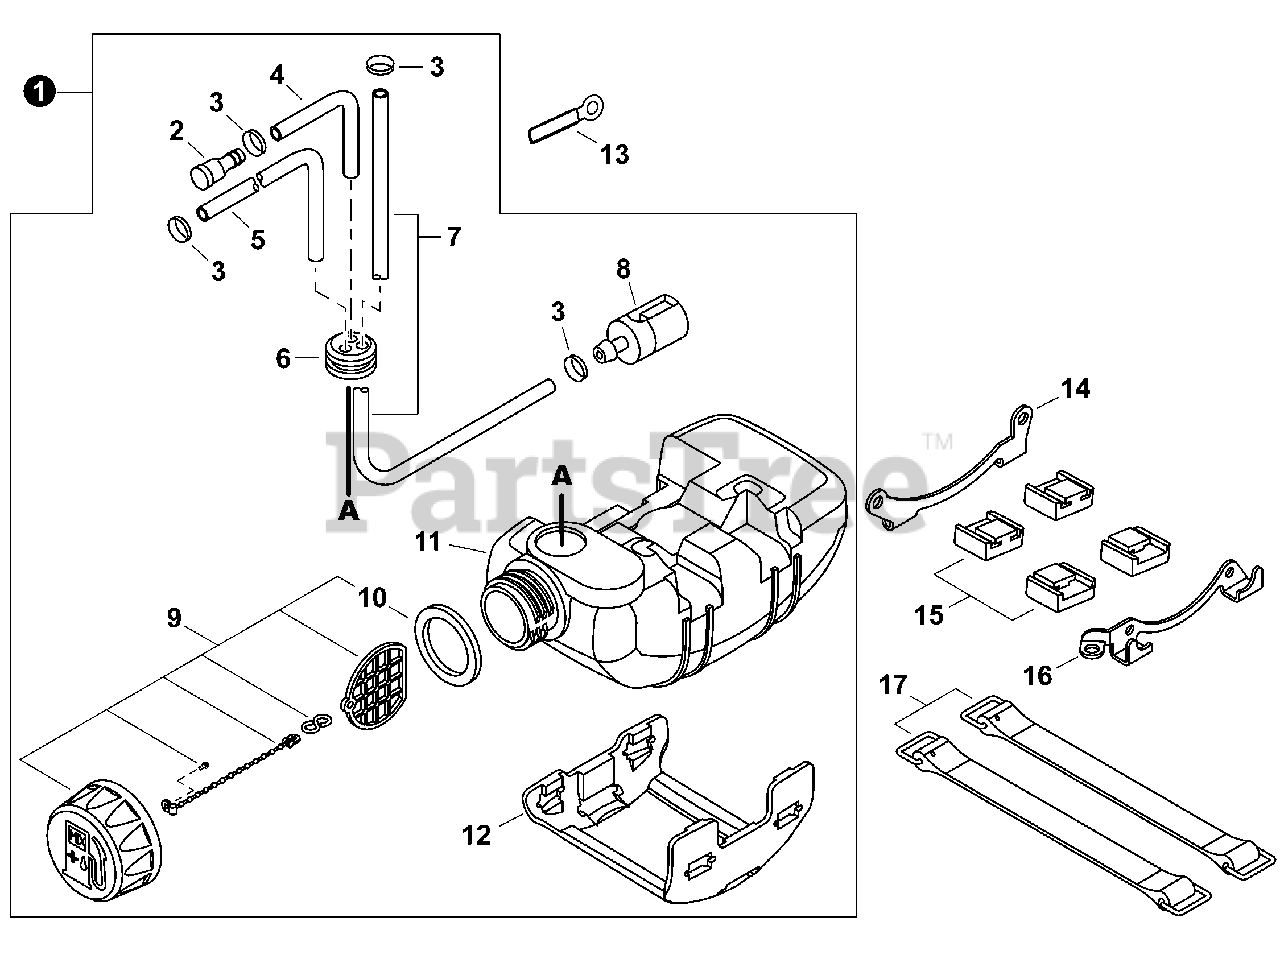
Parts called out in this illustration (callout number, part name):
1	TANK ASSY, FUEL
2	VENT ASSY
3	CLIP 6
4	PIPE 3x6x90 MM
5	PIPE, FUEL 3x6x50 YELLOW
6	GROMMET, FUEL
7	PIPE, FUEL 3x5x260 BLACK
8	FILTER, FUEL
9	CAP ASSY, FUEL
10	GASKET, FUEL CAP
11	TANK, FUEL
12	GUARD, FUEL TANK
14	BRACKET M
15	CUSHION, FUEL TANK
16	BRACKET S
17	STRAP, FUEL TANK
